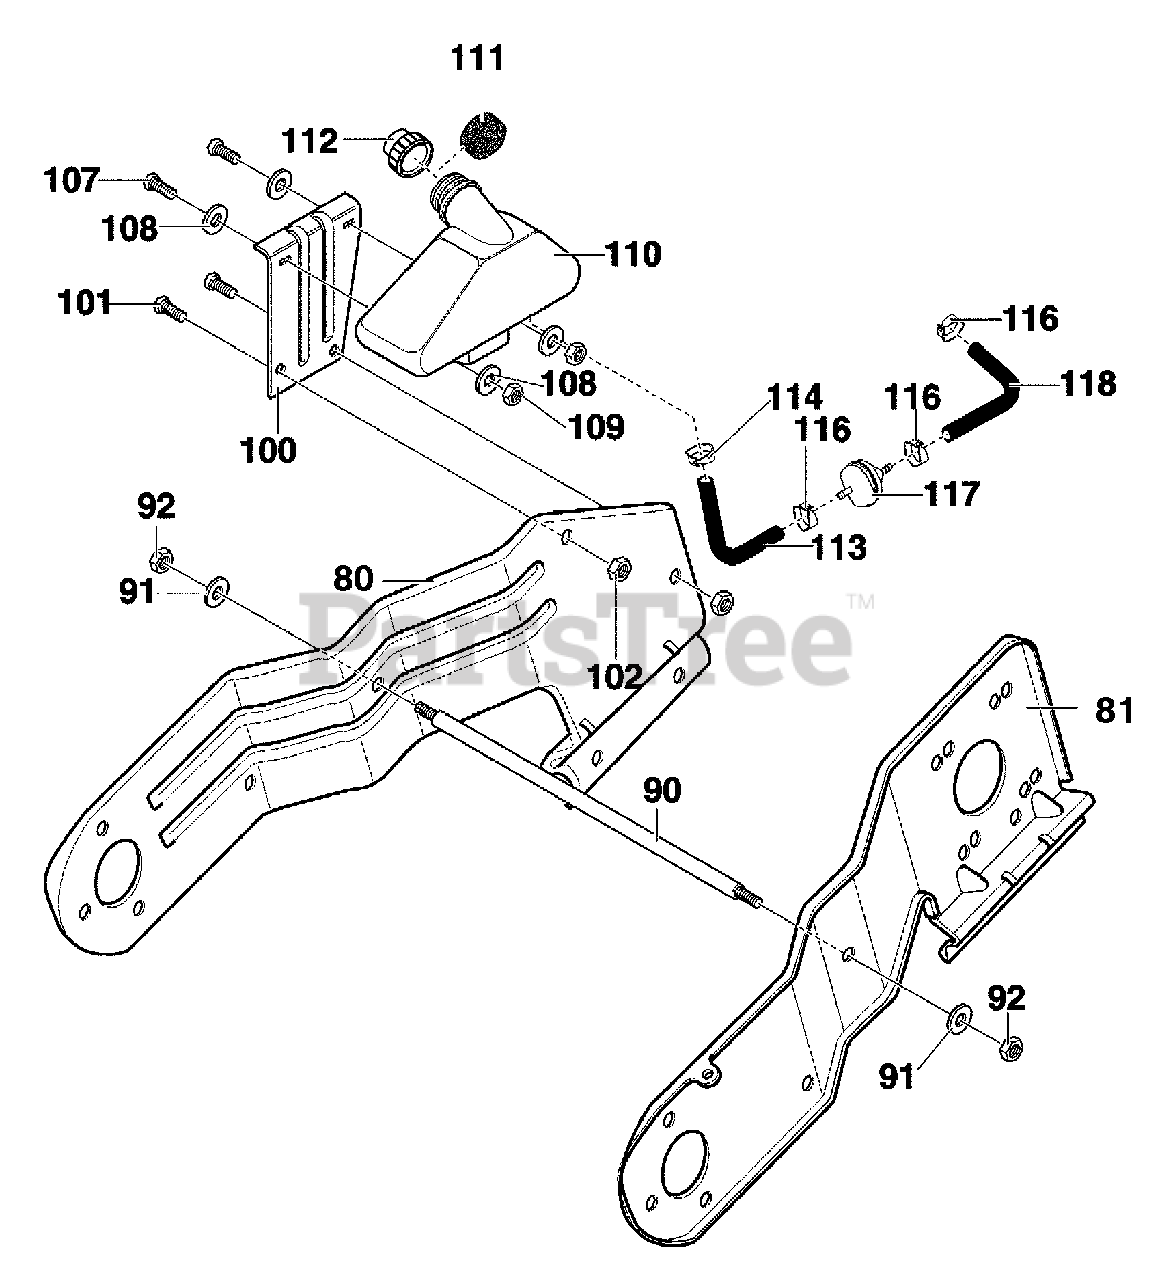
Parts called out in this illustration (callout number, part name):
80	FRAME, SIDE SUPT STEEL RH
81	FRAME, SIDE SUPT STEEL LH
90	ROD, SUPPORT
91	WASHER
92	NUT, 3/8-16 HEX
100	BRACKET, GAS TANK
101	SCREW, 1/4-20X.75
102	NUT, 1/4-20 HEX
107	SCREW, 1/4-20X.75
108	WASHER, FLAT
109	NUT, 1/420 HEX
110	TANK, FUEL
111	RING, FOAM FUEL TANK
112	CAP, GAS
113	TUBING 8 IN.
114	CLAMP, HOSE SCREW
116	CLAMP, HOSE
117	FILTER IN LINE
118	TUBING, 6 IN.
